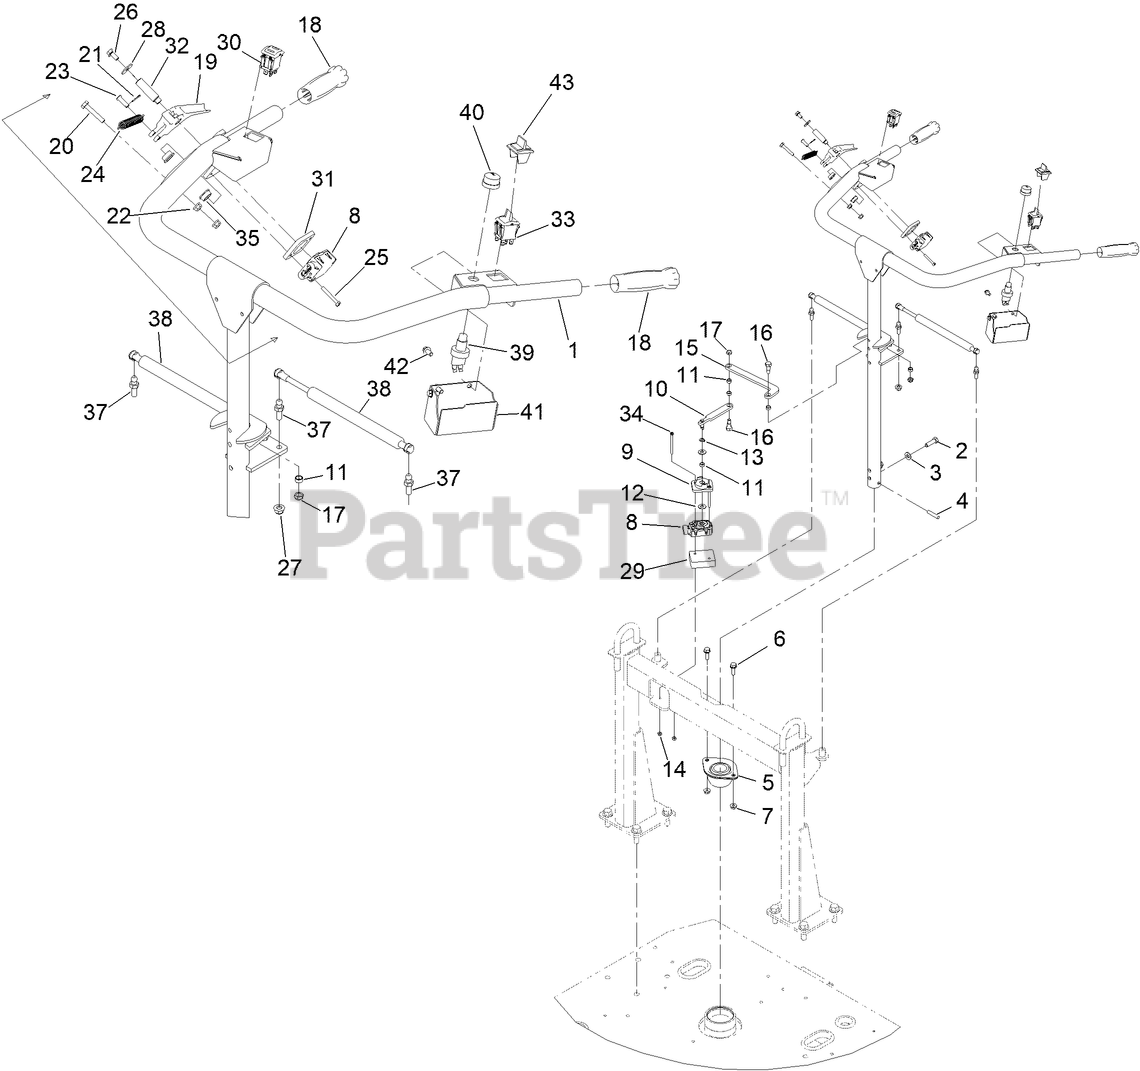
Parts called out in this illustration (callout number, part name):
1	HANDLE ASM [BLACK]
2	SCREW-HH
3	WASHER-HARDENED
5	SPHERICAL BEARING ASM
6	SCREW-HHF
7	NUT-FLANGE
8	SENSOR-POSITION
9	MOUNT-LINKAGE
10	LINKAGE ASM
11	BUSHING
12	WASHER
13	RING-RETAINING
14	NUT-LOCK, NI
15	LINKAGE-STEERING
16	BOLT-SHOULDER
17	NUT-LOCK, NI
18	GRIP-VINYL, BLACK
19	HANDLE
20	CAPSCREW
21	PIN-COTTER
22	NUT-FLANGE, NI
23	PIN-CLEVIS
24	SPRING-EXTENSION
25	SCREW-SHH
26	SCREW-HWH
27	NUT-HF, NI
28	WASHER-PLAIN
29	SPACER, STEERING-SENSOR
30	SWITCH-DIRECTIONAL
31	PLATE-MOUNT, LINKAGE
32	SHAFT-SENSOR
33	SWITCH,(ON)OFF(ON),PINNED,CB
34	SCREW-SHH
35	BUSHING
37	STUD-BALL
38	DAMPER-GAS
39	SWITCH-HORN
40	NUT-WEATHERPROOF
41	COVER-SWITCH
42	SCREW-HWH
43	BOOT,K2 PADDLE SWITCH
